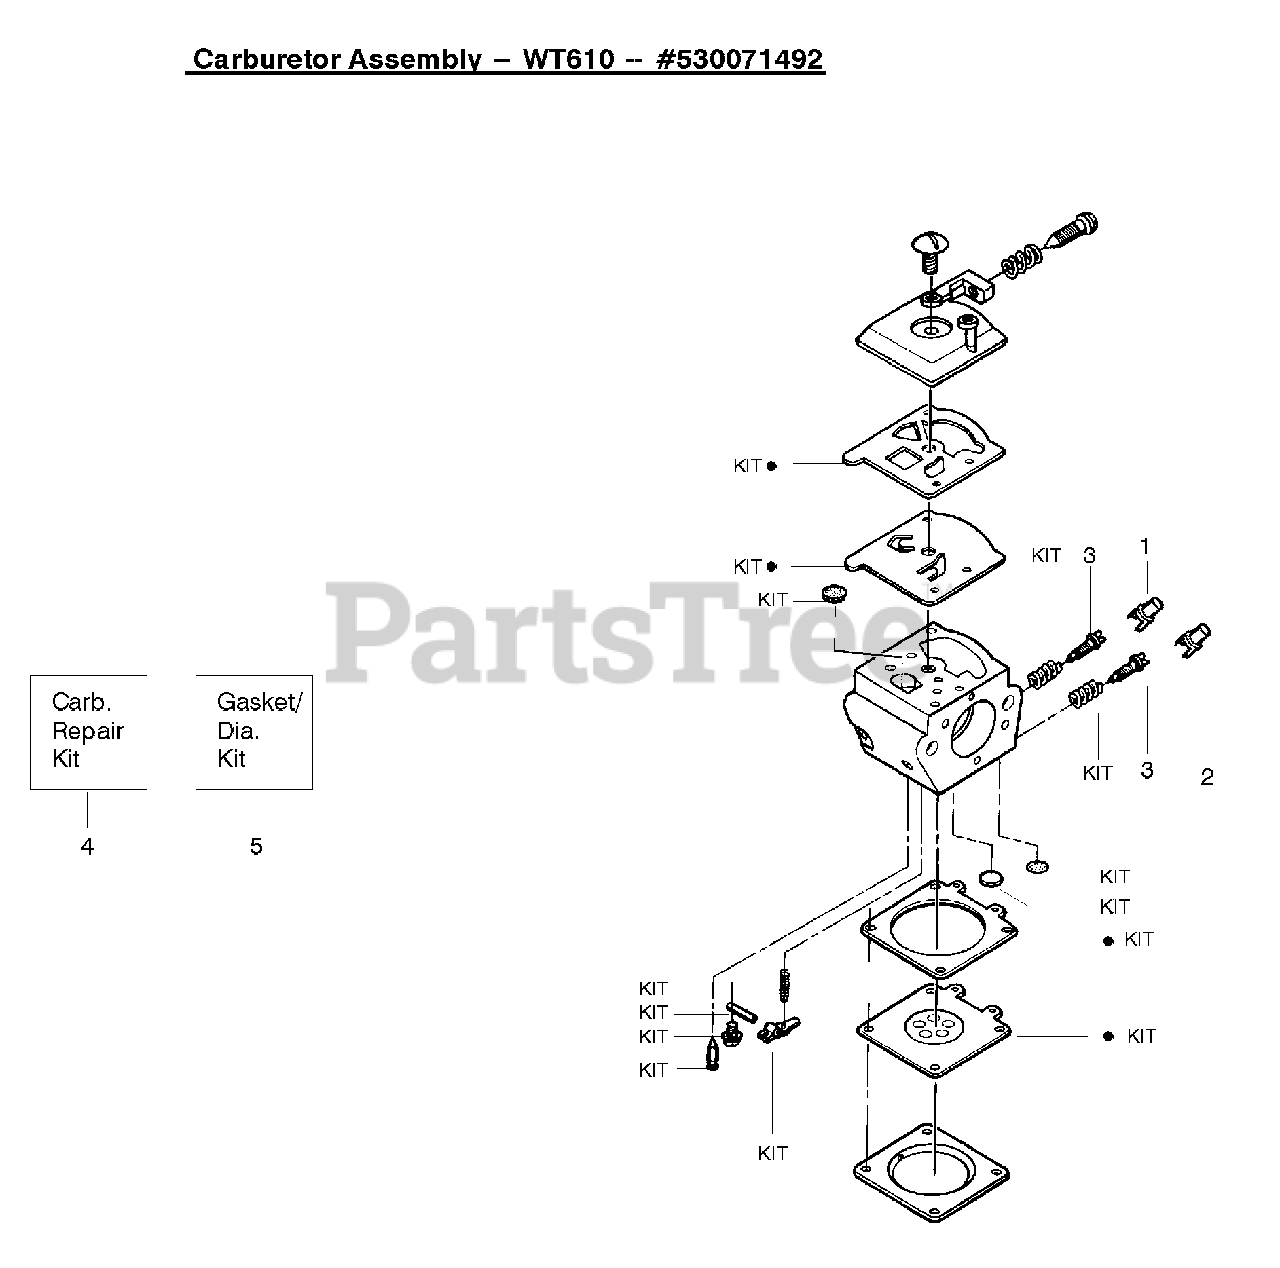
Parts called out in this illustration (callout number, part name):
1	Limiter-CapHigh
2	Limiter Cap-Low
3	Needle-High/low speed
4	Kit-Carburetor Repair
5	Kit-Gasket Diaphragm
